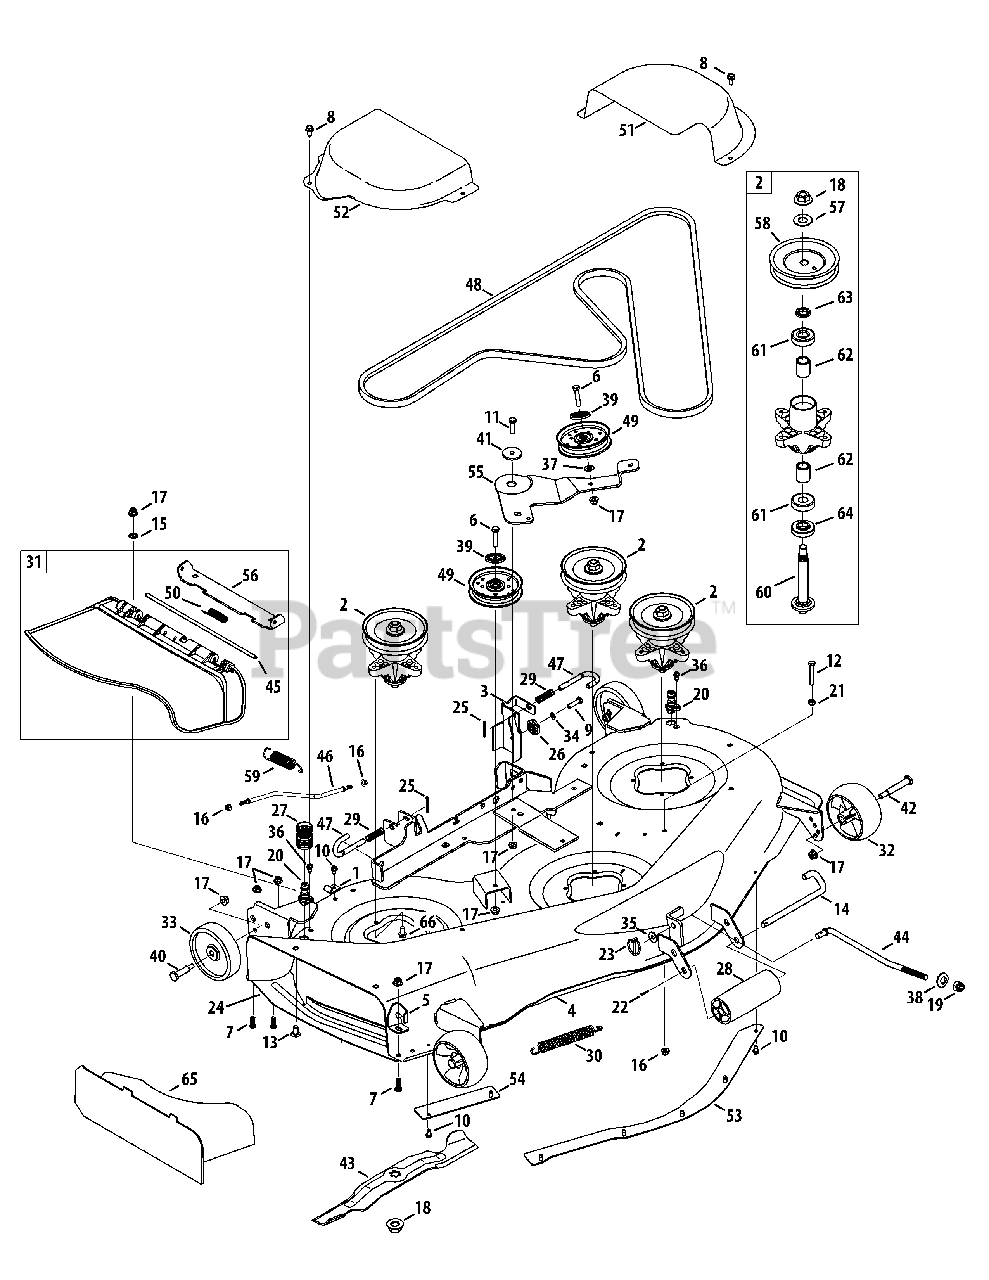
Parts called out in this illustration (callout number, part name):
1	Retainer Hook Brkt.
2	Spindle Assembly
3	Deck Hanger Bracket Ass'y
5	Chute Deflector Stop
6	Hex Screw 3/8-16 x 1.75
7	Screw, 3/8-16 x 1.0
8	SCREW 5/16-18 x .750
9	Hex Bolt 5/16-18 x 1.25
10	Hex Wash S-Tapp Scr 1/4-20 x .50
11	Hex Bolt 3/8-16 x 1.25
12	Hex Hd Cap Scr. 5/16-18 x 2.0 Gr. 5
13	CARRIAGE BOLT 3/8-16 x .75
14	Roller Pin
15	Push Nut 3/8
16	Flange Locknut 5/16-18 Gr. F, Nylon
17	Flange Lock-Nut 3/8-16 Gr. F Nylon
18	HEX NUT
19	Flexlock Nut 1/2-13
20	Deck Water Nozzle
21	Hex Nut 5/16-18 hd. (Gr. t5)
22	Cotter Pin 3/32 x 1.0
23	Lynch Pin, .1875
24	Finger Guard
25	Cotter Pin 1/8" Dia x 1.25
26	Deck Adjustment Gear
27	Water Nozzle Adaptor
28	Front Roller
29	Compression Spring .535 OD x 1.75" Lg.
30	Extension Spring .94 x 6.74
31	Chute Ass'y
32	Deck Wheel 5.0
33	PLASTIC WHEEL 5X1.38
34	L-Wash 5/16 ID
35	Flat Washer .531 ID x 1.25 OD x .100
36	Shoulder Screw 1/4-20 x 0.50
37	Flat Washer .406 ID x .875 OD x .059
38	Cupped Washer .63 x 1.25 x .18
39	Pulley Cap
40	Shoulder Bolt .498 Dia x 1.53 x 3/8-16
41	Spacer, Shoulder .884 x .190
42	Shoulder Screw
43	Blade 17.90
44	Front Deck Lift Rod
45	Hinge Pin .3125 x 7.96
46	Deck Sway Rod
47	Deck Release Pin
48	V-Belt
49	Idler Pulley
50	Torsion Spring
51	LH Belt Cover
52	RH Belt Cover
53	Deck Skirt Center
54	Deck Shirt RH
55	Idler Bracket
56	Chute Bracket
57	Flat Washer .760 ID x 1.50 OD x .120
58	Deck Pulley
59	Extension Spring 1.15 OD x 5.99
60	Spindle Shaft
61	Ball Bearing 20 x 47 x 14:6204:DS
62	Spacer .800 x 1.10 x 1.322
63	Spacer .790 x 1.25 x 1.75
64	Spacer .79 x 1.82 x .55
65	Mulching Plug
66	Hex. TT Screw 5/16-18 x .75
